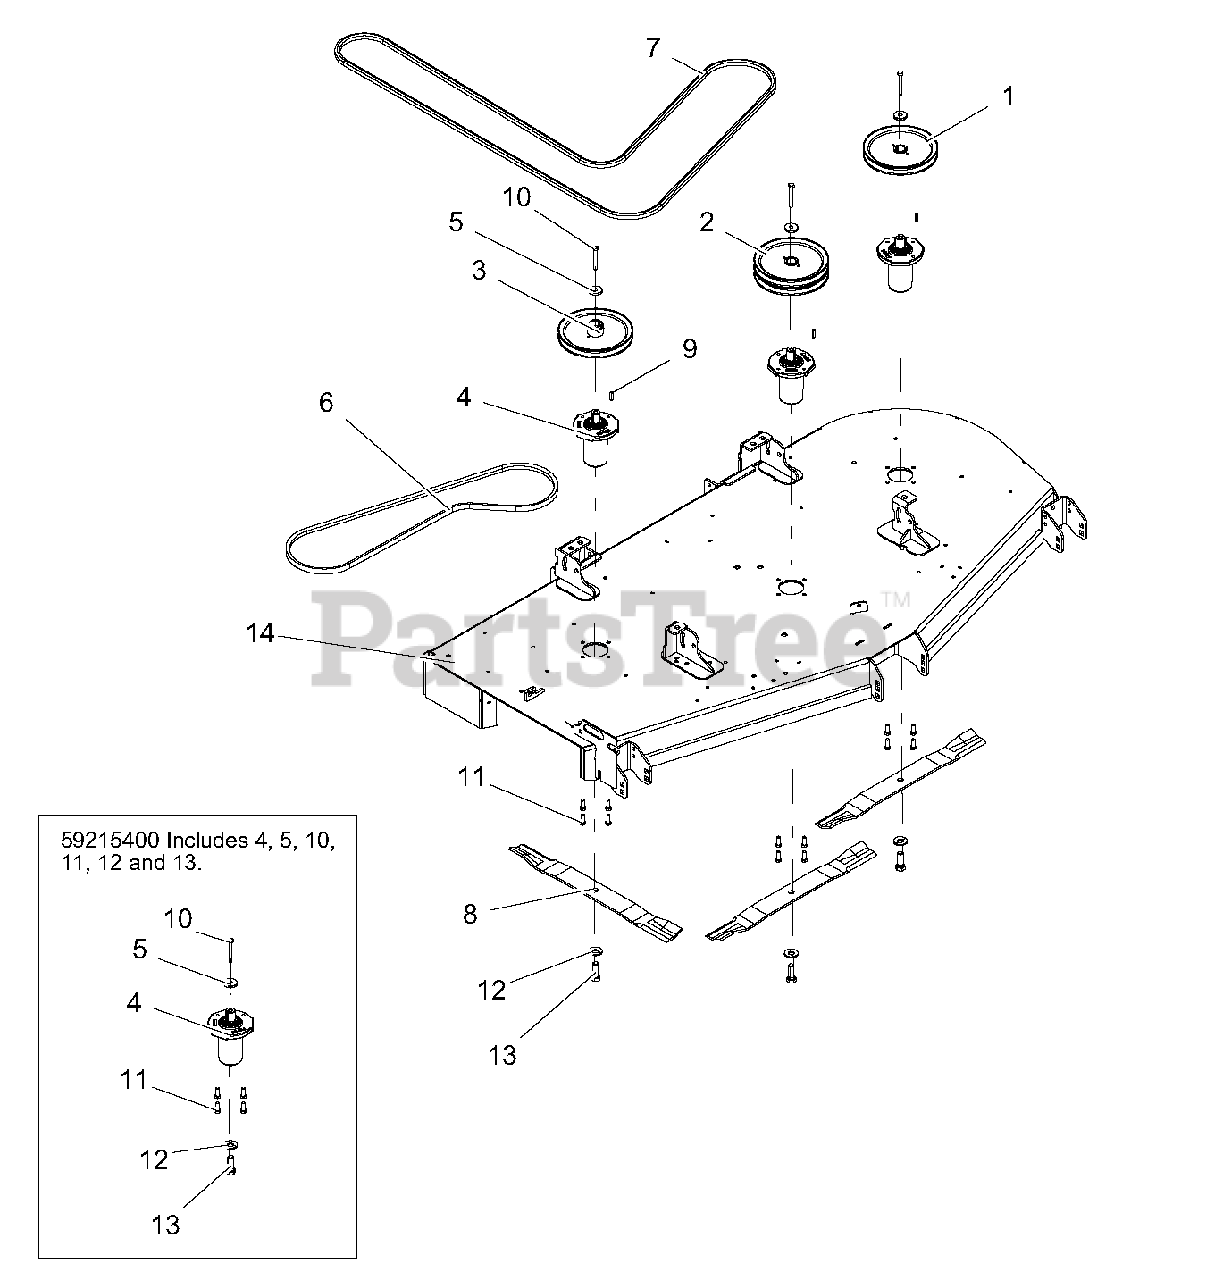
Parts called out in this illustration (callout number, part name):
1	SHEAVE-SINGLE 1.00" X 8.25" OD-BLACK
2	SHEAVE-DOUBLE 1.00"ID X 8.25"OD-BLACK
3	SHEAVE, SINGLE 1.00" ID X 8.25" OD-BLACK
4	SERVICE, ASM SPINDLE- DUCTILE
5	RETAINER, SHEAVE SPINDLE
6	V-BELT, B-COGGED
7	HEX BELT, BB-WRAPED
8	BLADE, MOWER 72" (24.5" LG)
9	KEY-SQ .250X.250X1.00 RC 40-50
10	BLT-HEX .38-16X2.75 GR8 YWZC
11	BLT-HEX .38-16X1.00 GR5 YWZC EP30
12	WSHR, BLVL .63X1.625X.14
13	BLT, HEX .62-18X1.75 GR8 YWZC
14	72" SIDE DISCH DECK W/SAFETY DECALS
